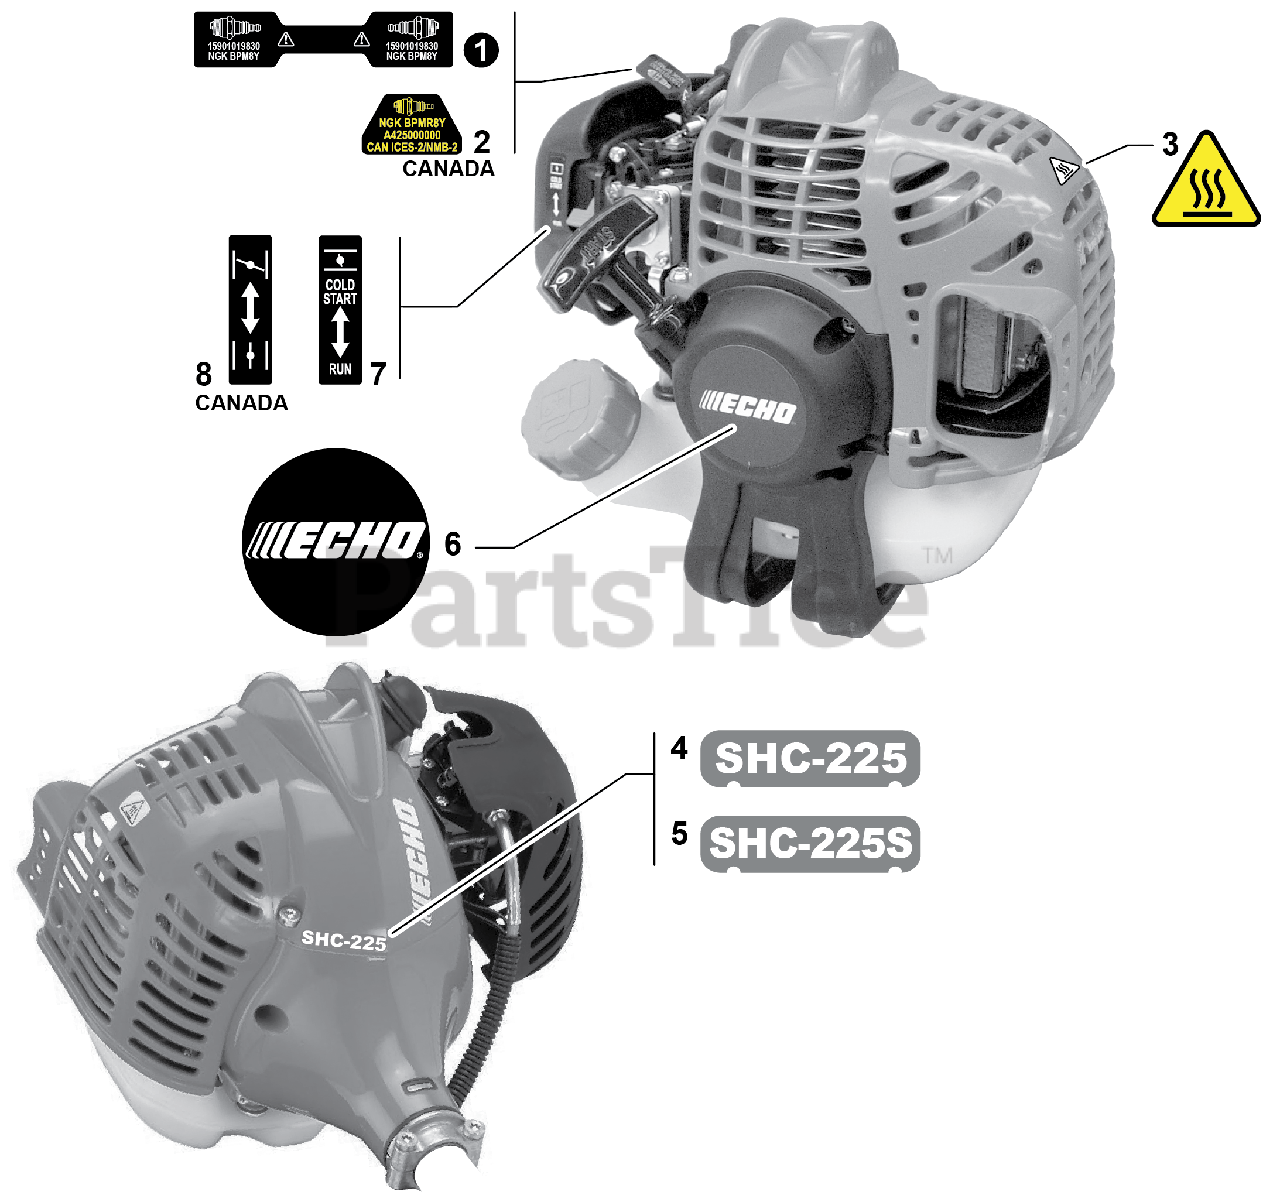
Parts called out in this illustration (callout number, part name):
1	LABEL, SPARK PLUG - BPM8Y
2	LABEL, SPARK PLUG - BPMR8Y
3	LABEL, CAUTION - HOT
4	LABEL, MODEL - SHC-225
5	LABEL, MODEL - SHC-225S
6	LABEL, RECOIL STARTER
7	LABEL, CHOKE
8	LABEL, CHOKE
